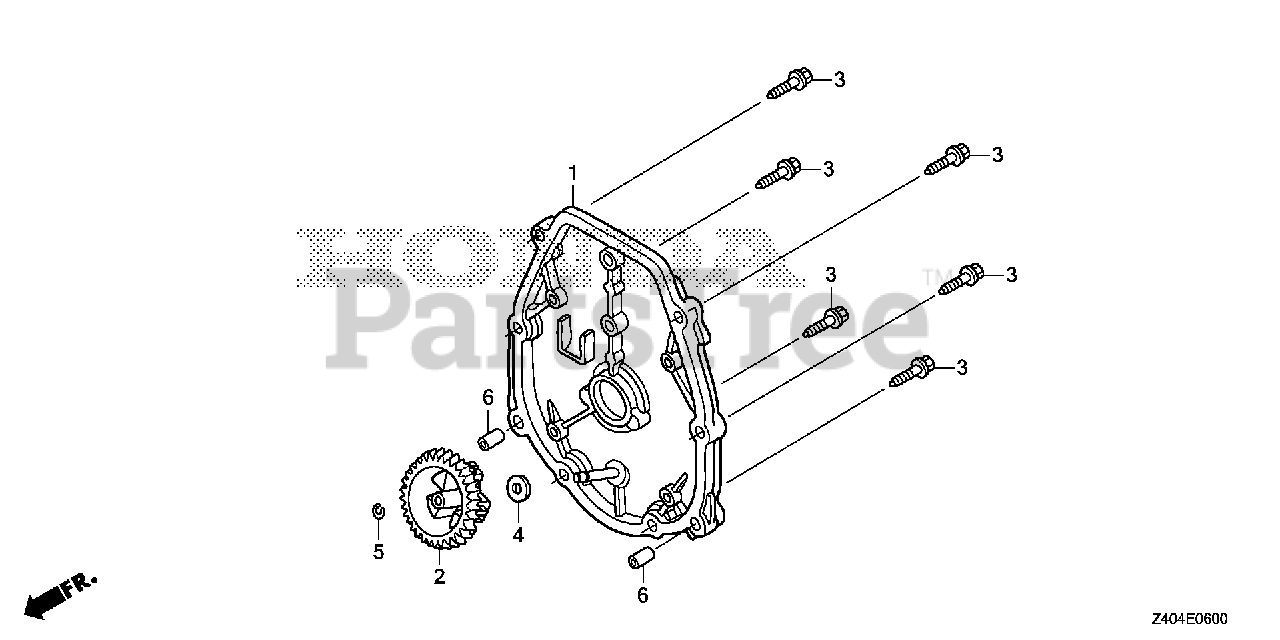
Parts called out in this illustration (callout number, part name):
1	COVER, CRANKCASE SIDE
2	HOLDER, GOVERNOR WEIGHT
3	BOLT, FLANGE (5X23)
4	WASHER (4.2X13)
5	CLIP, GOVERNOR HOLDER
6	PIN, DOWEL (6X10)
